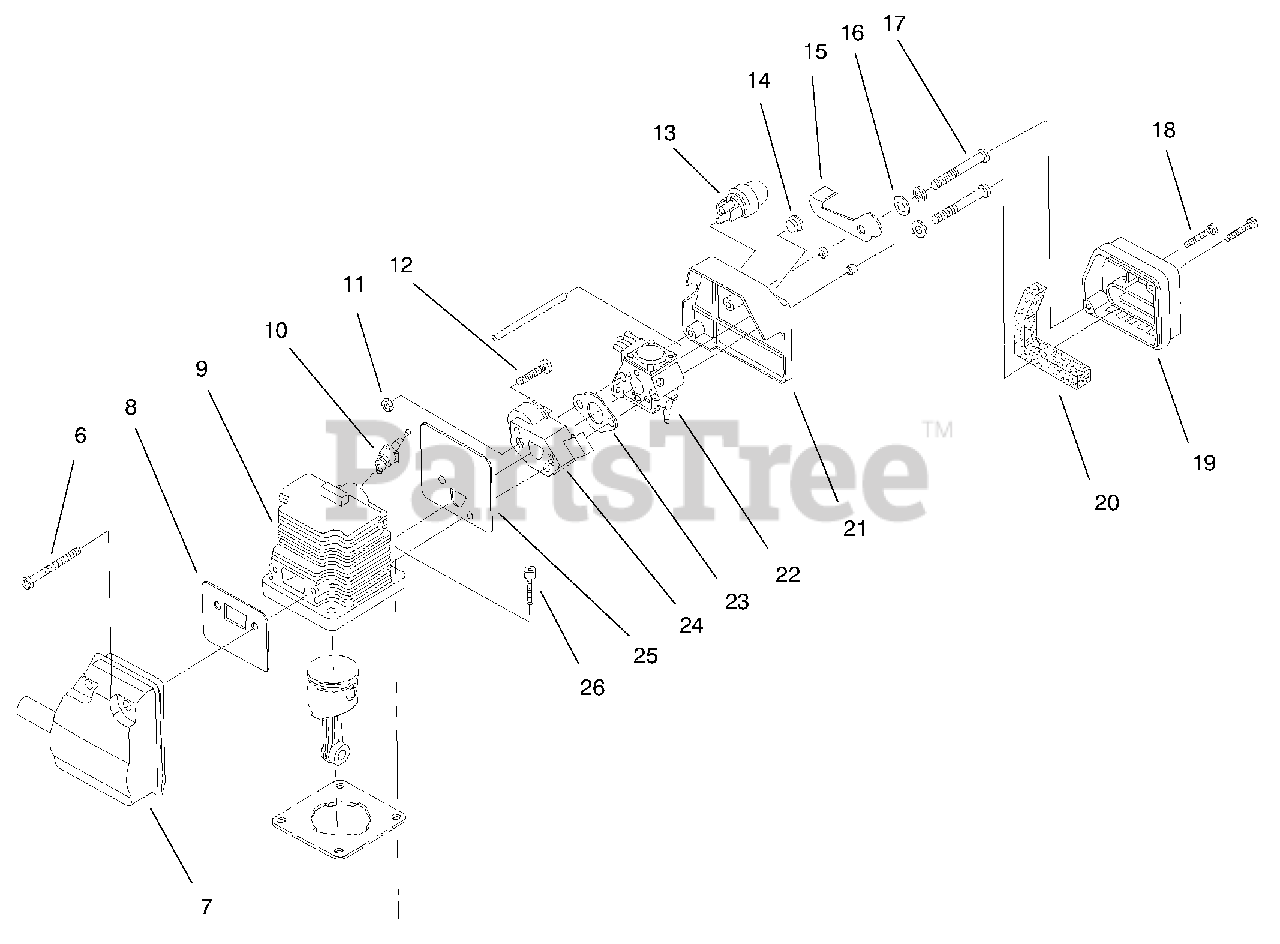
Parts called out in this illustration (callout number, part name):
6	MUFFLER MOUNTING SCREWS
7	MUFFLER ASSEMBLY
8	MUFFLER GASKET
9	CYLINDER
10	SPARK PLUG
11	SPACER NUT SET
12	SPACER SCREW SET
13	PRIMER & HOSE ASM
14	SWITCH PLUG
15	CHOKE LEVER
16	WAVEY WASHER
17	CARB MOUNTING ASM
18	Screw
19	AIR CLEANER COVER
20	FOAM AIR FILTER ELEMENT
21	Air Cleaner Base Asm.
22	ASM - CARBURETOR
23	CARB.GASKET(PK.10=1)
24	CARBURETOR SPACER ASM
25	CYL/CARB SPACER GASKET
